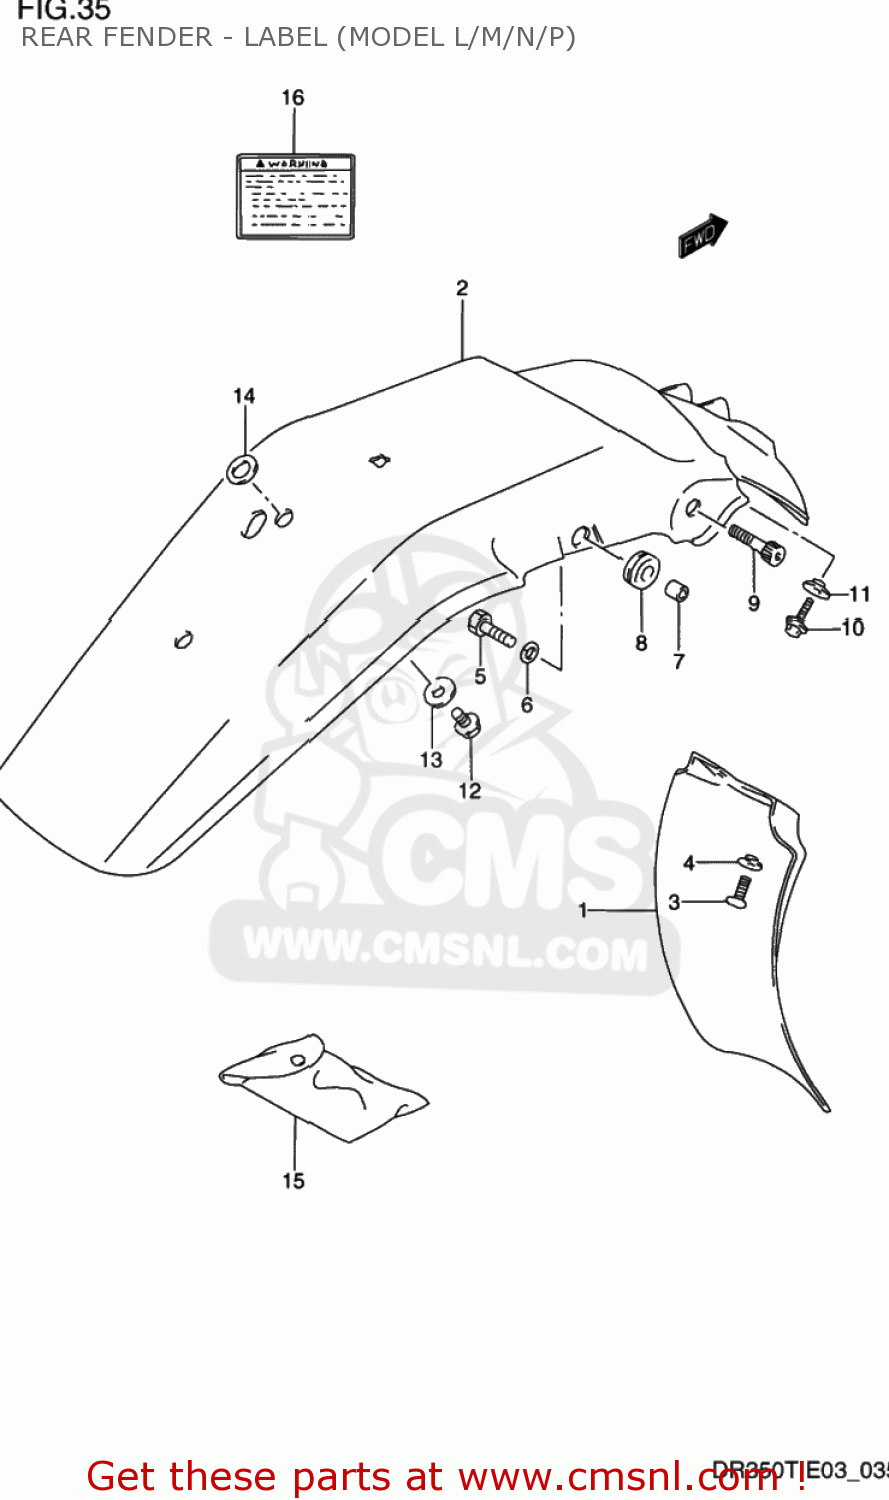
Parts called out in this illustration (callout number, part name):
1	BODY,RR FENDER FR
2	FENDER,REAR
3	SCREW 6X12
4	WASHER
5	BOLT
6	WASHER,LOCK
7	SPACER (8.8X12X7)
8	CUSHION
9	BOLT(8X30)
10	BOLT
11	WASHER
12	BOLT
13	WASHER
14	WASHER(14.2X26X1.2)
15	TOOL ASSY
16	LABEL
